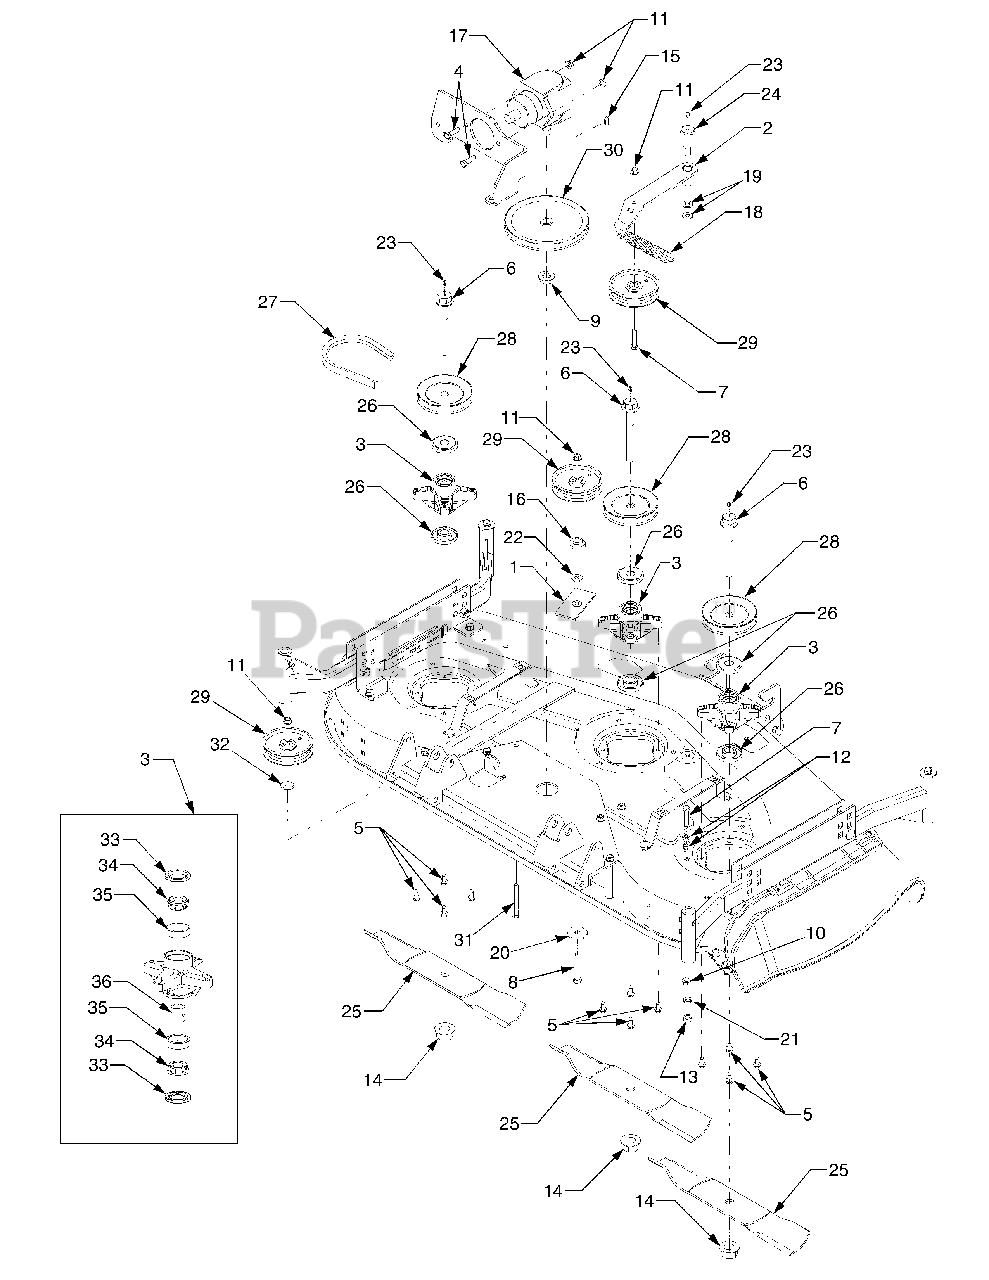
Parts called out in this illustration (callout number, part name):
1	Assembly, Spacer
2	Bracket, Idler
3	Assembly, Spindle Includes Ref. Nos. 33 thru 36
4	Screw, Hex Cap 3/8-16 x 1.25 GR5
5	Screw, Hex Wash Hd Tapp 5/16-18 x .75
6	Bolt, Spindle, 3/4-16 x 4.25
7	Screw, Hex Cap 3/8-16 x 1.75 GR5
8	Screw, Hex Cap 3/8-16 x 3.0 GR8
9	Nut , Hex Flanged 5/8-18
10	Nut, Jam Lock 3/8 -16 GR5
11	Nut, Flange Lock 3/8-16
12	Nut, Hex Jam, 3/8-16 GR5
13	Nut, Hex 7/16-14
14	Nut, Hex Flange, 3/4-16
15	Key, Hi-Pro
16	Spacer, Shoulder
17	Drive, Right Angle
18	Spring, Extension 6.14" Lg.
19	Washer, Flat, .45 x 1.25 x .164
20	Washer, Flat .406" I.D.
21	Washer, Lock 7/16" I.D.
22	Washer, Flat .47 x .75 x .06
23	Fitting, Lube
24	Bolt, Shoulder .68" Dia. x 1.59 .
25	Blade, High Lift 18.5" Lg.
26	Spacer, Deck Spindle
27	Belt, “V" 120" Lg.
28	Pulley, “V"
29	Pulley, Flat Idler
30	Pulley, Drive
31	Screw, Carriage, 3/8-16 x 2.25
32	Washer, Flat, .38 x .93 x .11 Hd
33	Seal, Oil
34	Bearing, Cone
35	Cup, Bearing
36	Spacer, Bearing
